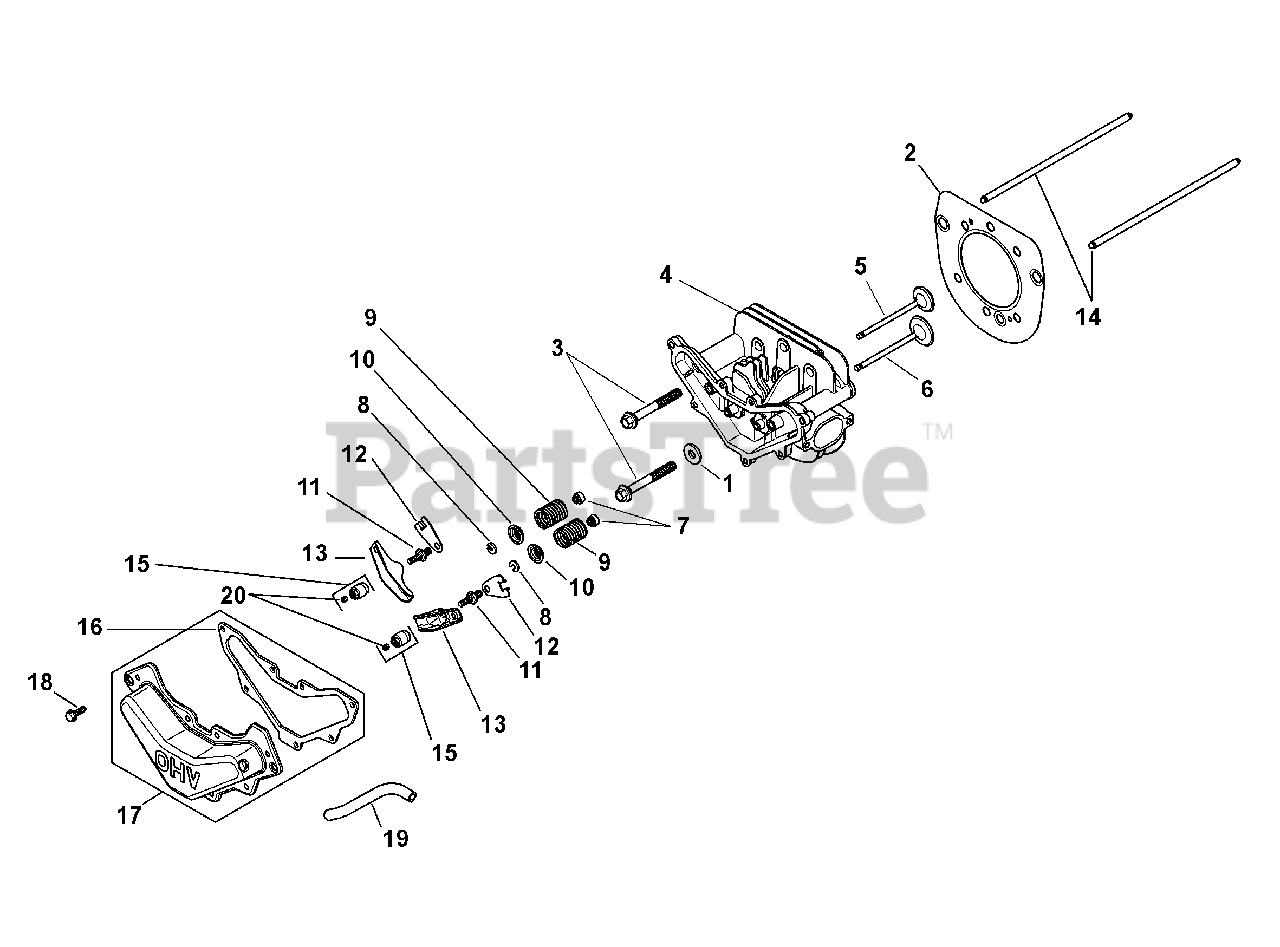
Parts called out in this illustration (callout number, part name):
1	Flat Washer, 13/32
2	Cylinder Head Gasket Kit
3	Flange Screw, M10 X 1.5 X 80
4	Cylinder Head Kit
5	Exhaust Valve
7	Valve Stem Seal
8	Retainer Lock
10	Valve Spring Cap
12	Push Rod Guide Plate
15	Rocker Pivot Assembly
16	Valve Cover Gasket
17	Valve Cover Kit
18	Flg. Thd. Frm. Screw, M6 X 1.0 X 20
19	Breather Hose
